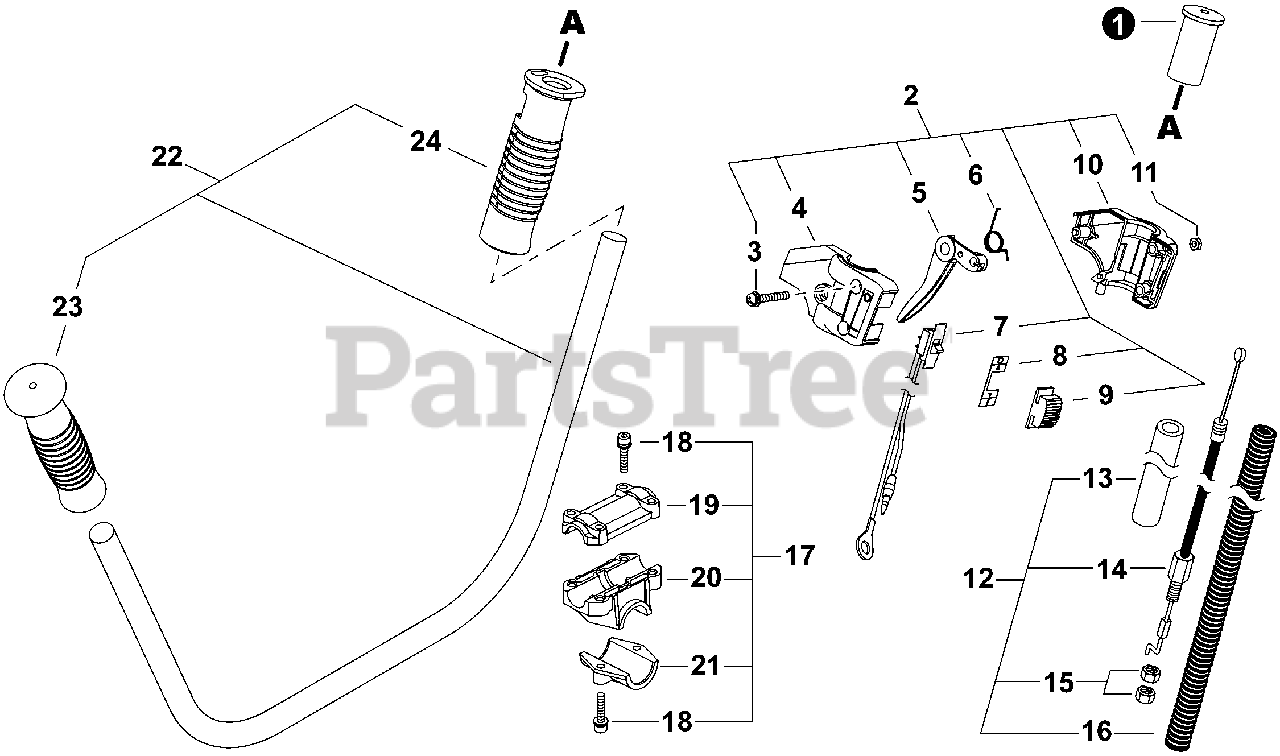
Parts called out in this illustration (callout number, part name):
2	THROTTLE CONTROL ASSY
3	SCREW M5x30
4	CONTROL HANDLE - LEFT
5	TRIGGER, THROTTLE
6	SPRING, RETURN
7	SWITCH, ON-OFF
8	PLATE, SWITCH
9	KNOB, SWITCH
10	CONTROL HANDLE - RIGHT
12	TUBE 5x8x20
13	CABLE ASSY, THROTTLE
14	CABLE, THROTTLE
16	TUBE, FLEXIBLE
17	BRACKET ASSY
18	BOLT M5x25
19	BRACKET, UPPER HANDLEBAR
20	BRACKET, LOWER HANDLEBAR
21	BRACKET, MOUNTING
22	HANDLEBAR ASSY
24	GRIP, THROTTLE
